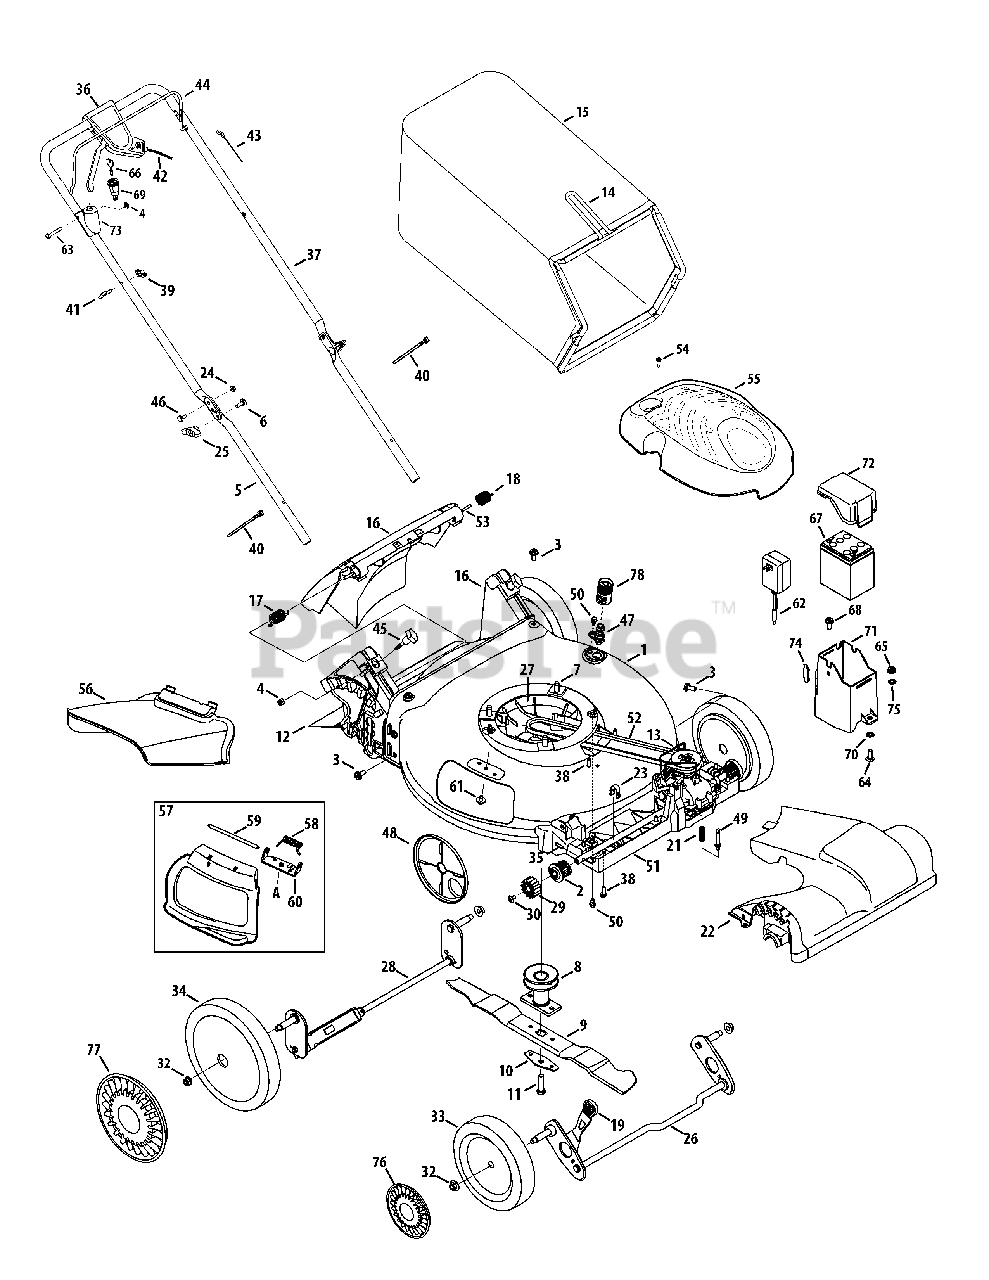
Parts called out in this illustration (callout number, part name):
1	Deck , 21"
1	Deck, 21"
2	Bearing Assembly
3	Screw, 5/16-14 x .750
4	Nut, Sq., 1/4-20
5	Lower Handle
6	Carriage Screw ,5/16-18
7	Screw, 3/8-16 x 1.00
8	Blade Adapter
9	Mulching Blade
10	Blade Bell Support
11	Screw, 3/8-24 x 1.50
12	Trailing Shield
13	Transmission Wire
15	Grass Bag
16	Rear Discharge Door Assembly
17	Torsion Spring - RH
18	Torsion Spring - LH
19	Adjustment Lever Knob
20	Screw, 1/4-20 x .500
21	Compression Spring
22	Front Cover
23	Front Axle Clip
24	Nut, Flange Lock, 1/4-20
25	Wing Knob
26	Front Axle Assembly
27	Engine Baffle
28	Rear Axle Assembly
29	Spur Gear, 14T - RH
29	Spur Gear, 14T - LH
30	Screw, 1/4-20 x .390
31	Transmission Assembly
32	Flange Lock Nut, 3/8-16
33	Front Wheel
34	Rear Wheel
35	Dowel Pin
36	Control Lever Assembly
37	Upper Handle
38	Screw, 1/4-15 x .750
40	Cable Tie
41	Rope Guide
42	Drive Cable
43	Control Cable
45	Wing Nut
46	Sldr. Screw, .375 x .126 x 1/4-20
47	Water Nozzle
48	Wheel Dust Cover
49	Spring Body
50	Screw., Shldr., 1/4-20 x .50
51	Lower Tray
52	V-Belt
53	Pivot Rod
54	Screw, #12-16 x 1.00
55	Engine Shroud, Oyster Gray
56	Side Discharge Chute
57	Mulch Plug (Incl. 58-60)
58	Torsion Spring
59	Hinge Pin
60	Chute Deflector Bracket
61	Screw, 1/4-20 x .500
62	Battery Charger
63	Screw, 1/4-20 x 1.75
64	Bolt, Carr., 5/16-18 x 1.00
65	Nut, Hexlk, 5/16-18
66	Key
67	Battery
68	Screw., Sldr., 5/16-14 x .972
69	Key Switch
70	Speed Nut
71	Battery Housing
72	Battery Housing Top
73	Electric Start Housing
74	Lid Seal
75	Washer, Bell, .340 x .872 x .080
76	Hubcap, Grey
77	Hubcap, 11", Grey
78	Water Nozzle Adapter
